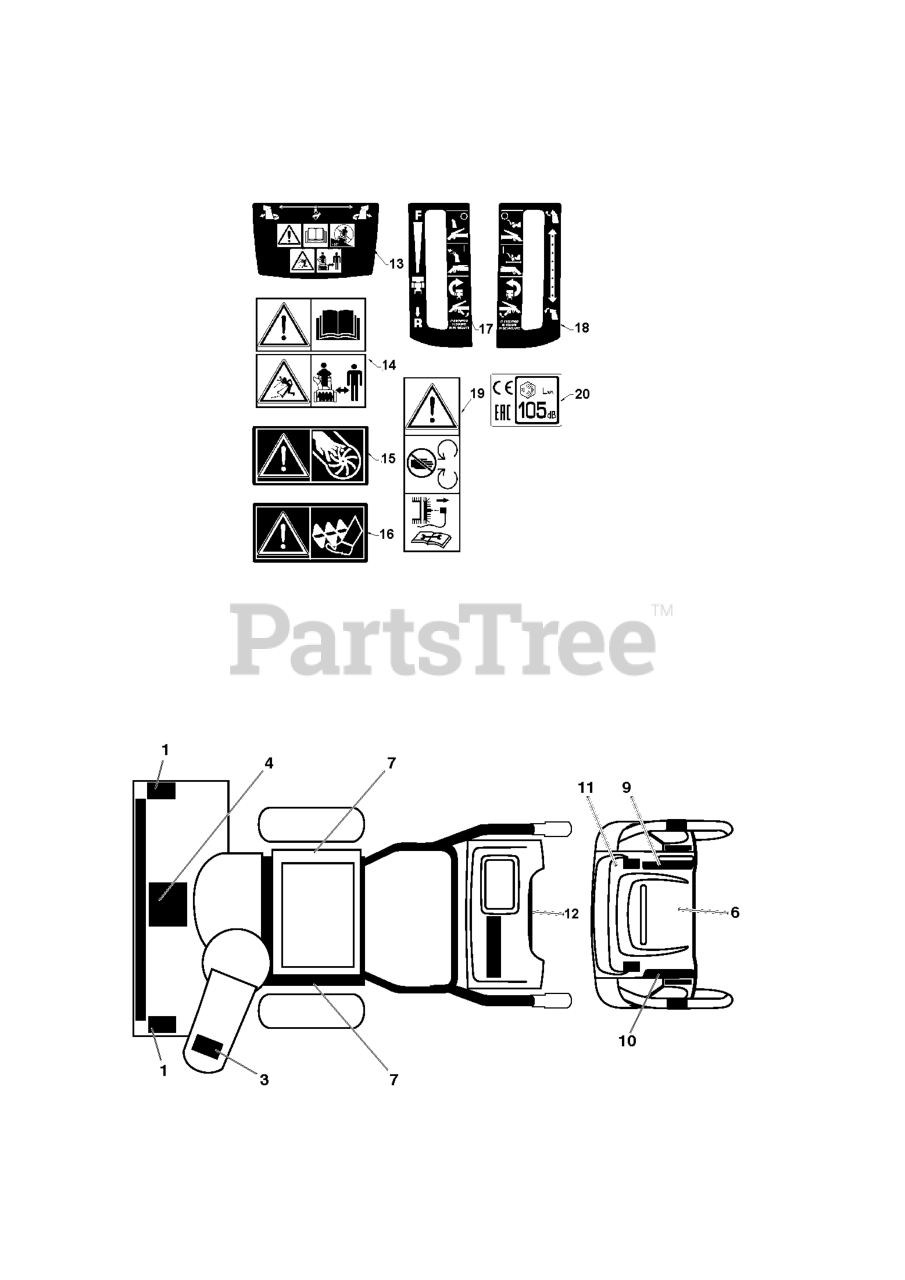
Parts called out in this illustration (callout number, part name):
1	DECAL.AUGER.SAFETY.
3	DECAL.CHUTE.SAFETY.EU/SC.17
3	DECAL.CHUTE.SAFETY.
4	DECAL.AUGER."
7	DECAL.BELT.GUARD.
9	DECAL CONSOLE DECAL DECAL.SNOW
10	DECAL CONSOLE DECAL DECAL.SNOW
11	DECAL.CONSOLE.HAND.WARMER
12	DECAL.NOISE.LEVEL.105DB/CE.EAC
14	DECAL.AUGER."
15	DECAL.CHUTE.SAFETY.
16	DECAL.AUGER.SAFETY.
17	DECAL CONSOLE DECAL DECAL.SNOW
18	DECAL CONSOLE DECAL DECAL.SNOW
19	DECAL.BELT.GUARD.
20	DECAL.NOISE.LEVEL.105DB/CE.EAC
